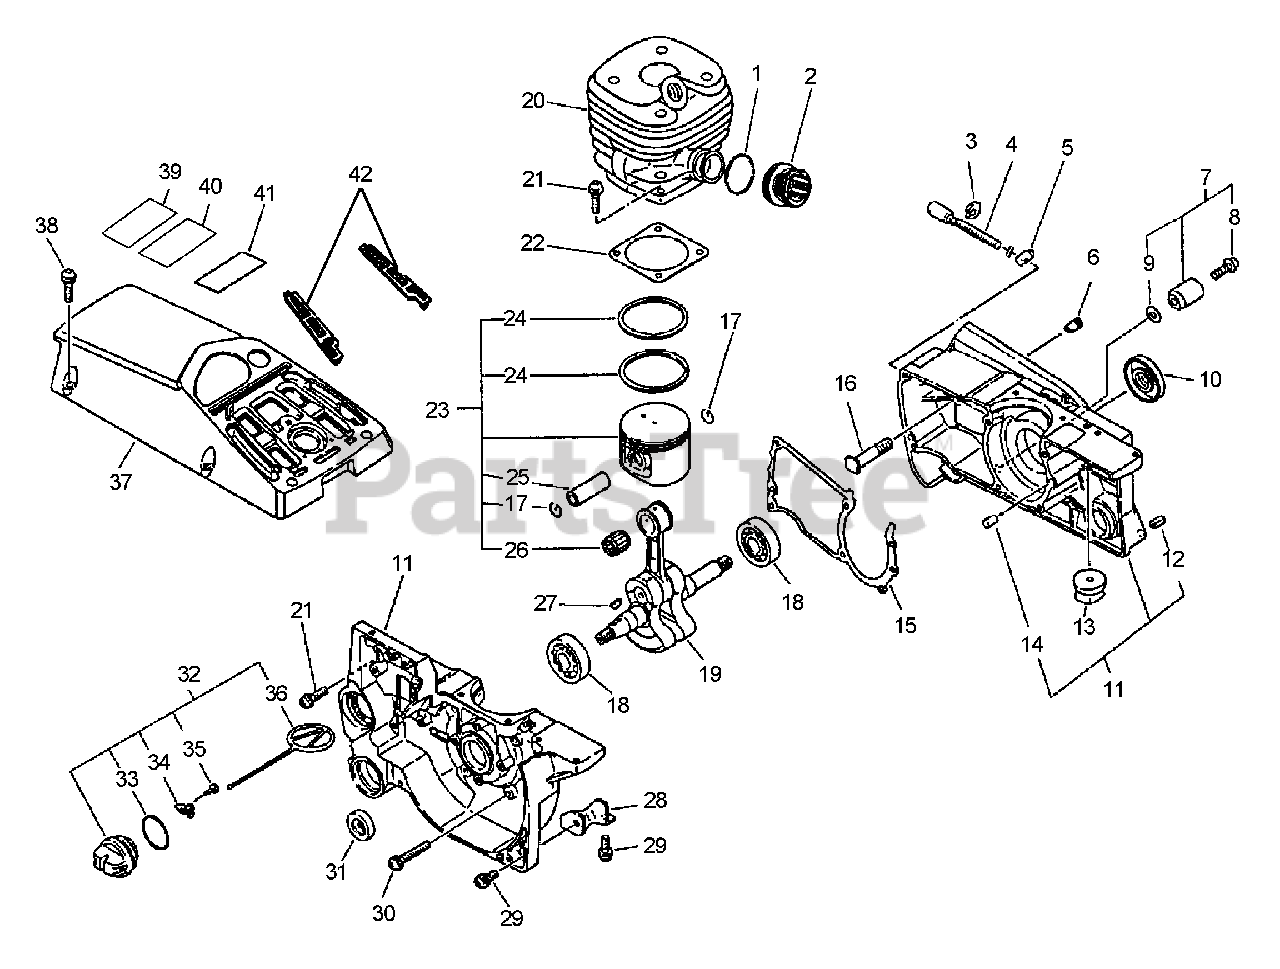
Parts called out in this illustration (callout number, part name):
2	BELLOWS, INTAKE
4	SCREW, TENSIONER
5	TENSIONER, CHAIN
6	VENT, TANK
7	CHAIN CATCHER KIT
8	SCREW - 5X18
9	WASHER - 5
10	SEAL, OIL
11	CRANKCASE KIT
12	PIN - SPRING -- 5X10
13	CUSHION - A
14	PIN - LOCATING
15	GASKET, CRANKCASE
16	STUD, GUIDE BAR
17	RING, RETAINING
18	BEARING, BALL - 6202
19	CRANKSHAFT ASSY
20	CYLINDER KIT
21	SCREW - 5X20
22	GASKET, CYLINDER
23	PISTON KIT
24	RING, PISTON
25	PIN, PISTON
26	BEARING, NEEDLE
29	SCREW - 5X14
30	SCREW - 5X35
31	SEAL, OIL
32	CAP ASSY
33	O-RING - 25
34	RETAINER
35	SCREW - 3X8
36	CONNECTOR, CAP
37	COVER, ENGINE
38	SCREW - 5X20
39	LABEL - BAR & CHAIN
40	LABEL - KICK BACK
41	LABEL - KICK BACK
42	DEBRIS FILTER KIT
